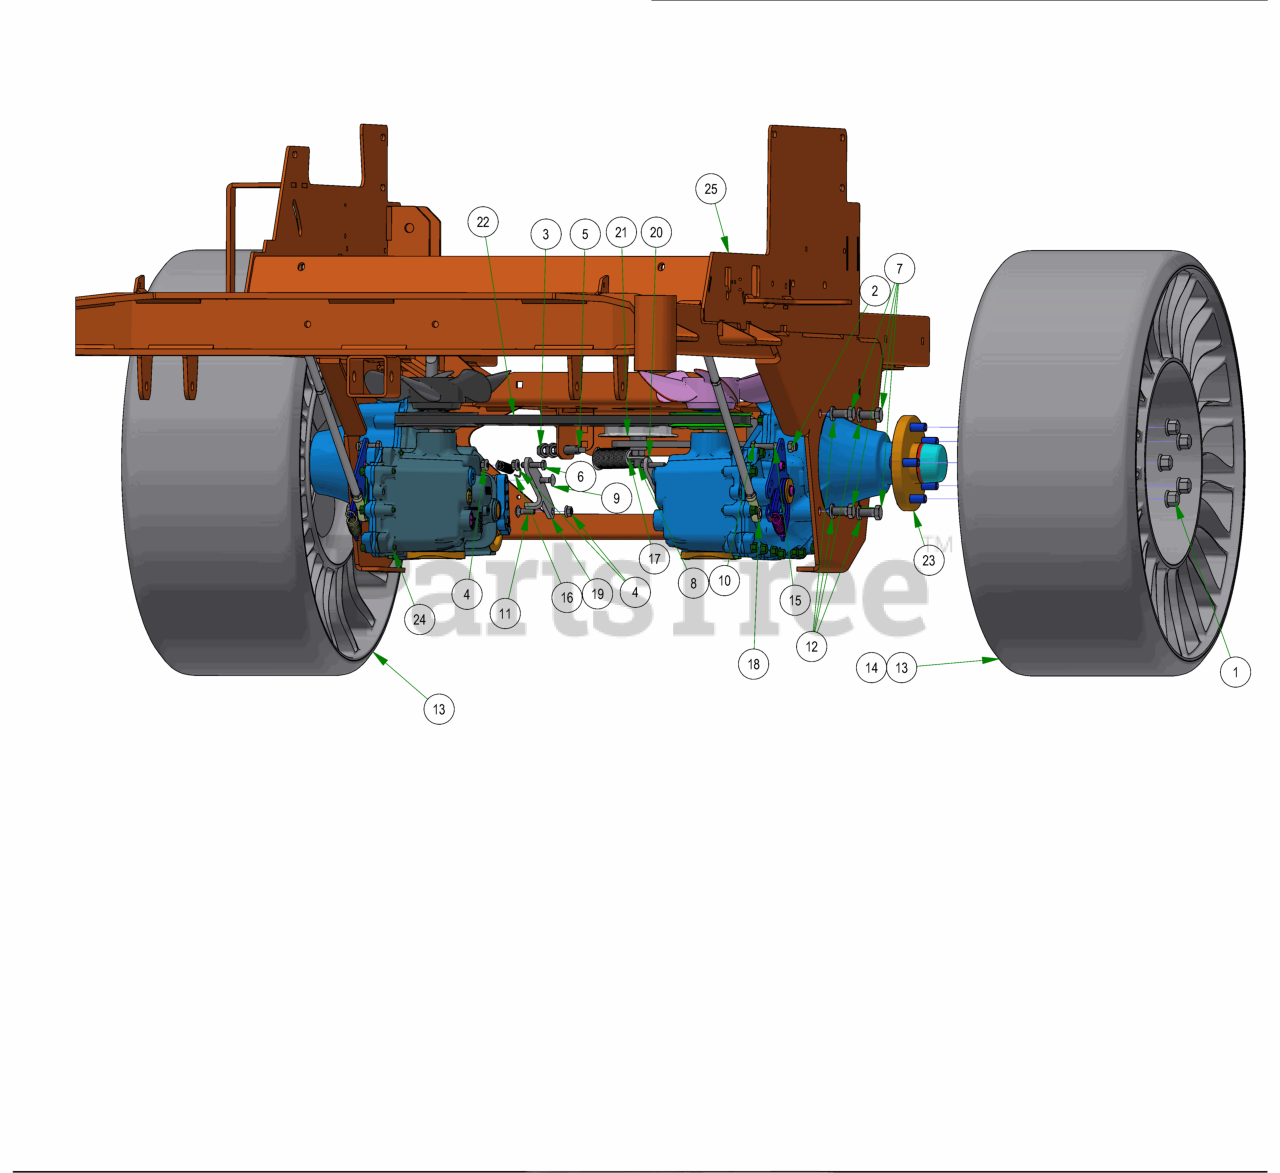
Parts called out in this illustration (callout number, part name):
1	Acorn Lug Nut
2	3/8-16 NYLON INSERT LOCKNUT ZINC
3	1/2-13 HEX NUT ZINC
4	5/16-18 NYLON INSERT FLANGE LOCKNUT ZINC
5	All Thread
6	5/16-18 X 1-1/4 HEX C/S (GR.5) ZC
7	1/2-13 X 1 HEX CAP SCREW (GR.5) ZINC
8	1/2-13 NYLON INSERT JAM LOCKNUT ZINC
9	5/16-18 X 1-1/4 CARRIAGE BOLT ZINC
10	3/8-16 X 1-1/4 HEX CAP SCREW (GR.5) ZINC
11	5/16-18 X 1 CARRIAGE BOLT (GR.8) ZINC
12	1/2 SPLIT LOCKWASHER (GR.8) ZINC/YELLOW
13	TWEEL, 24X12N12 ZTR 5ON4.5 BLACK 1.3IN OFFSET
14	24x12-12 Reaper Turf Tire & Wheel Assembly
15	Drive Arm Transaxle Spacer
16	Brake Spring
17	Deck spring big diameter
18	2024 Rebel Push Rod Assembly
19	5400 Transaxle Brake Adapter Plate RH v3
20	5400 Transaxle Brake Adapter Plate LH v3
21	2024 Rebel X Pump Idler
22	2019 Rebel Pump Belt
23	5400 TRANSAXLE LH
24	5400 TRANSAXLE RH
25	2023 Rebel Frame - Painted
